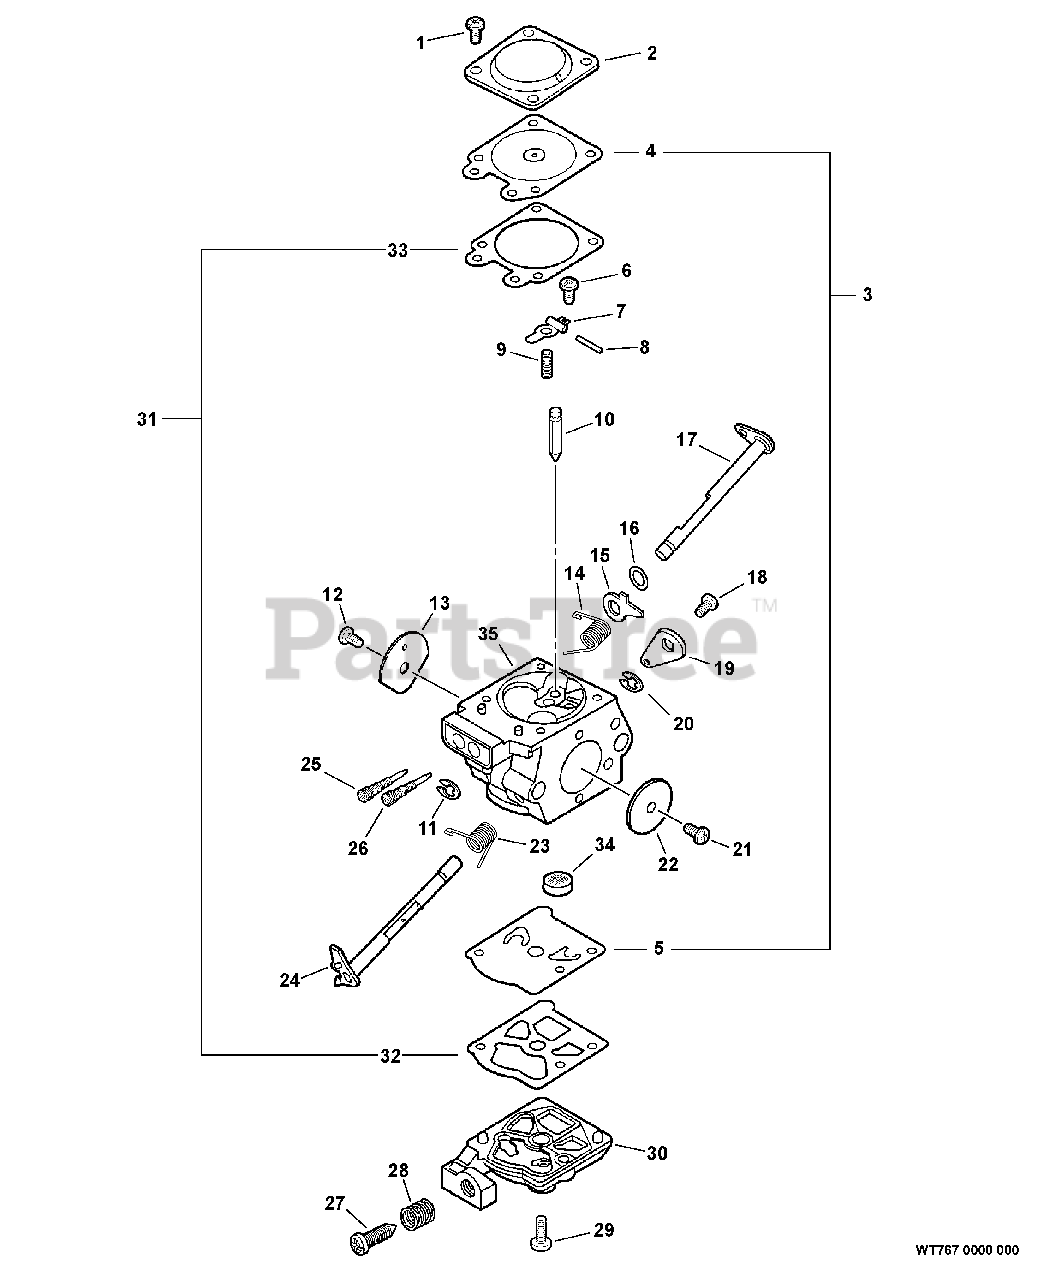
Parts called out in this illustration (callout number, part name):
1	SCREW
2	COVER, METERING DIAPHRAGM
3	DIAPHRAGM KIT
4	DIAPHRAGM, METERING
5	DIAPHRAGM, PUMP
6	SCREW, METERING LEVER PIN
7	LEVER, METERING
8	PIN, METERING LEVER
9	SPRING, METERING LEVER
10	VALVE, INLET NEEDLE
11	E-RING
12	SCREW, THROTTLE STOP
13	VALVE, CHOKE
14	ROD, CHOKE
15	LEVER, FAST IDLE
16	WASHER
17	SHAFT ASSY, CHOKE
18	SCREW, THROTTLE STOP
19	LEVER, THROTTLE
20	E-RING
21	SCREW, THROTTLE STOP
22	VALVE, THROTTLE
23	SPRING, THROTTLE RETURN
24	SHAFT, THROTTLE
25	NEEDLE, HIGH SPEED
26	NEEDLE, LOW SPEED
27	SCREW, IDLE ADJUST
28	SPRING, IDLE ADJUST
29	SCREW
30	COVER ASSY, PUMP
31	GASKET KIT
32	GASKET, PUMP
33	GASKET, METERING DIAPHRAGM
34	SCREEN, FUEL INLET
35	BODY, CARBURETOR
